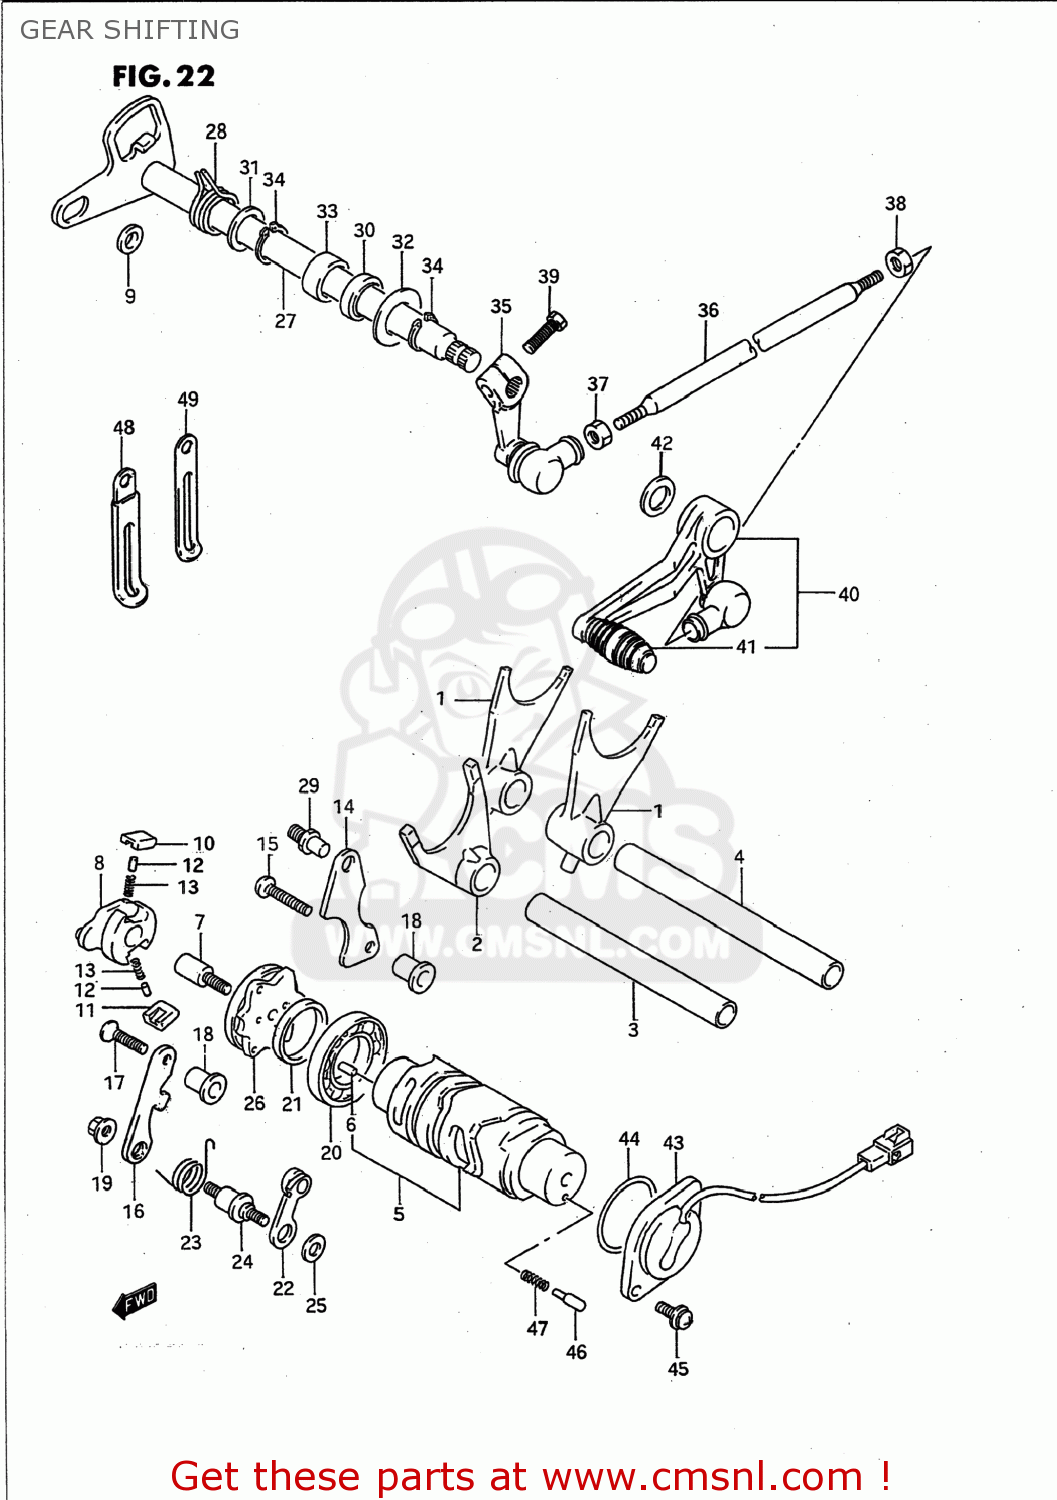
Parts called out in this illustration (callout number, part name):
1	FORK,GEAR SHIFT NO.1
2	FORK,GEAR SHIFT NO.3
3	SHAFT,GEAR SHIFT FORK
4	SHAFT,GEAR SHIFT FORK(L:128)
5	CAM,GEAR SHIFT
6	PIN
7	PIN,SHIFT CAM DRIVEN GEAR
8	SHIFTER,GEAR SHIFT CAM
9	SPACER(7X10X5)
10	PAWL,GEAR SHIFT NO.1
11	PAWL,GEAR SHIFT NO.2
12	PIN(5X8)
13	SPRING
14	LIFTER,GEAR SHIFT PAWL
15	SCREW 6X30
16	GUIDE,GEAR SHIFT CAM
17	SCREW
18	SPACER(6.1X10X16)
19	NUT
20	BEARING
21	WASHER(25X32X3)
22	STOPPER,GEAR SHIFT CAM
23	SPRING,STOPPER ARM
24	SUPPORT,CAM STOPPER ARM
25	WASHER
26	PLATE,GEAR SHIFT CAM
27	SHAFT,GEAR SHIFT
28	SPRING
29	STOPPER,GEAR SHIFT CAM
30	SEAL,OIL(14X22X6)
31	WASHER,THRUST
32	WASHER
33	BEARING(14X20X12)
34	CIRCLIP
35	ARM,GEAR SHIFT LINK
36	ROD,GEAR SHIFT LINK
37	NUT
38	NUT
39	BOLT
40	LEVER ASSEMBLY,GEAR SHIFTING
41	RUBBER,GEAR SHIFT PEDAL
42	WASHER(18X24X1)
43	TERMINAL BASE ASSY,NEUTRAL
44	O RING(D:2.4,ID:36.5)
45	SCREW
46	PIN(5X15.5)
47	SPRING
48	CLAMP
49	CLAMP
